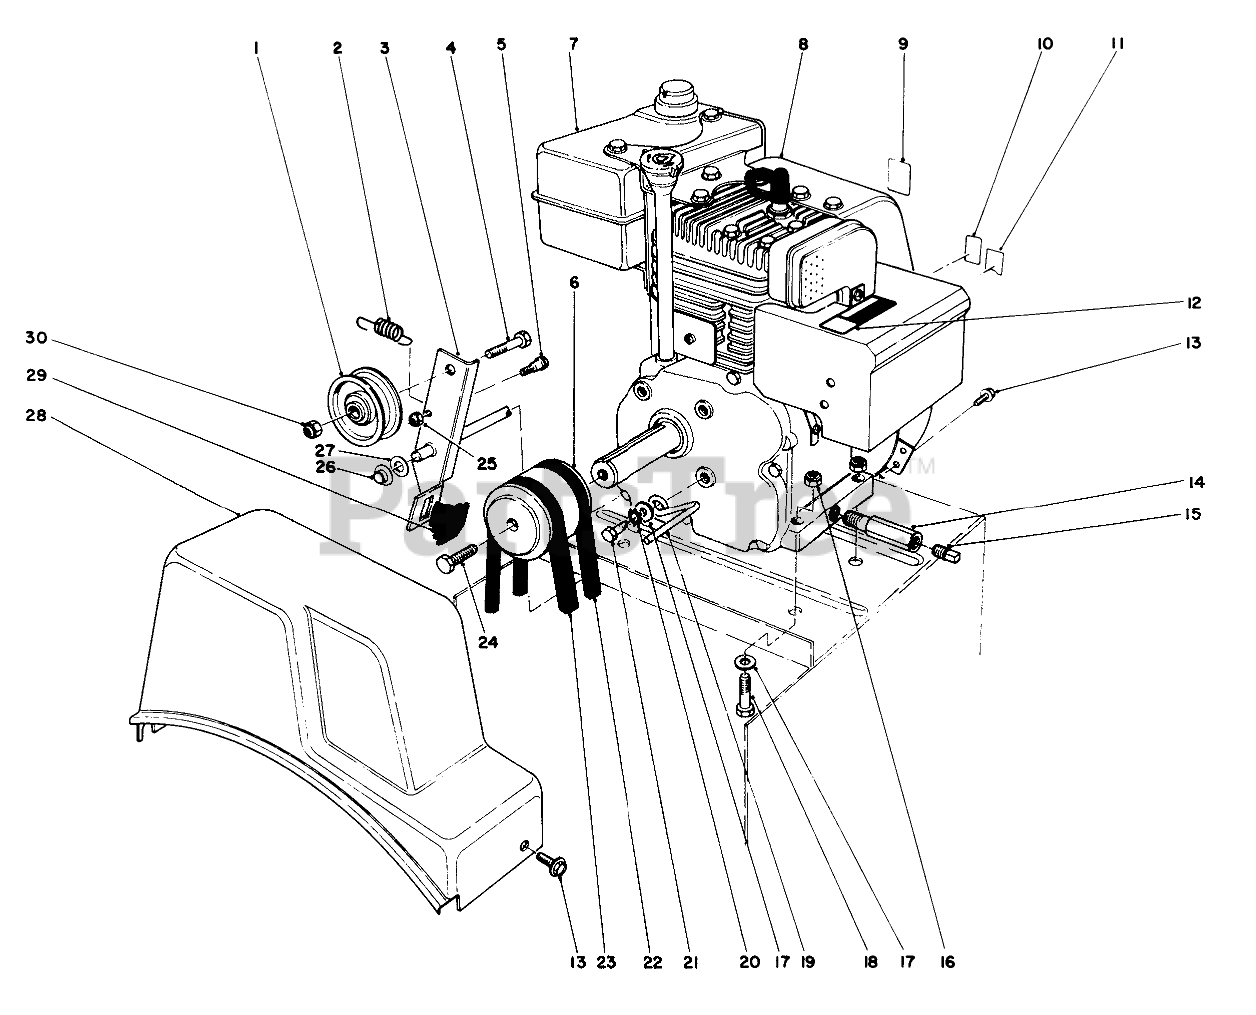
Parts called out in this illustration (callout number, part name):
1	PULLEY-IDLER
2	SPRING
3	Auger Clutch (Incl. Ref. #29)
4	SCREW-HH
5	BOLT-SHOULDER
6	PULLEY-ENGINE
7	GAS TANK 2 QT W CAP
9	DECAL-PRIMER
10	THROTTLE DECAL, INT'L
11	DECAL-CHOKE
12	DECAL-HOT SURFACE, WARNING
13	SCREW-HWH
14	PIPE-NIPPLE
15	CAP-PIPE
16	NUT-LOCK, NI
17	WASHER-PLAIN
18	SCREW-HH
19	RETAINER-BELT
20	WASHER-LOCK
21	SCREW-HH
22	V BELT-3L, TRACTION
23	V-BELT (29.50 INCH)
24	SCREW-SPECIAL
25	NUT-LOCK, NI
26	RETAINER-PUSH ON
27	WASHER-FLAT
28	COVER-BELT
29	PAD-BRAKE
30	NUT-LOCK, NI
